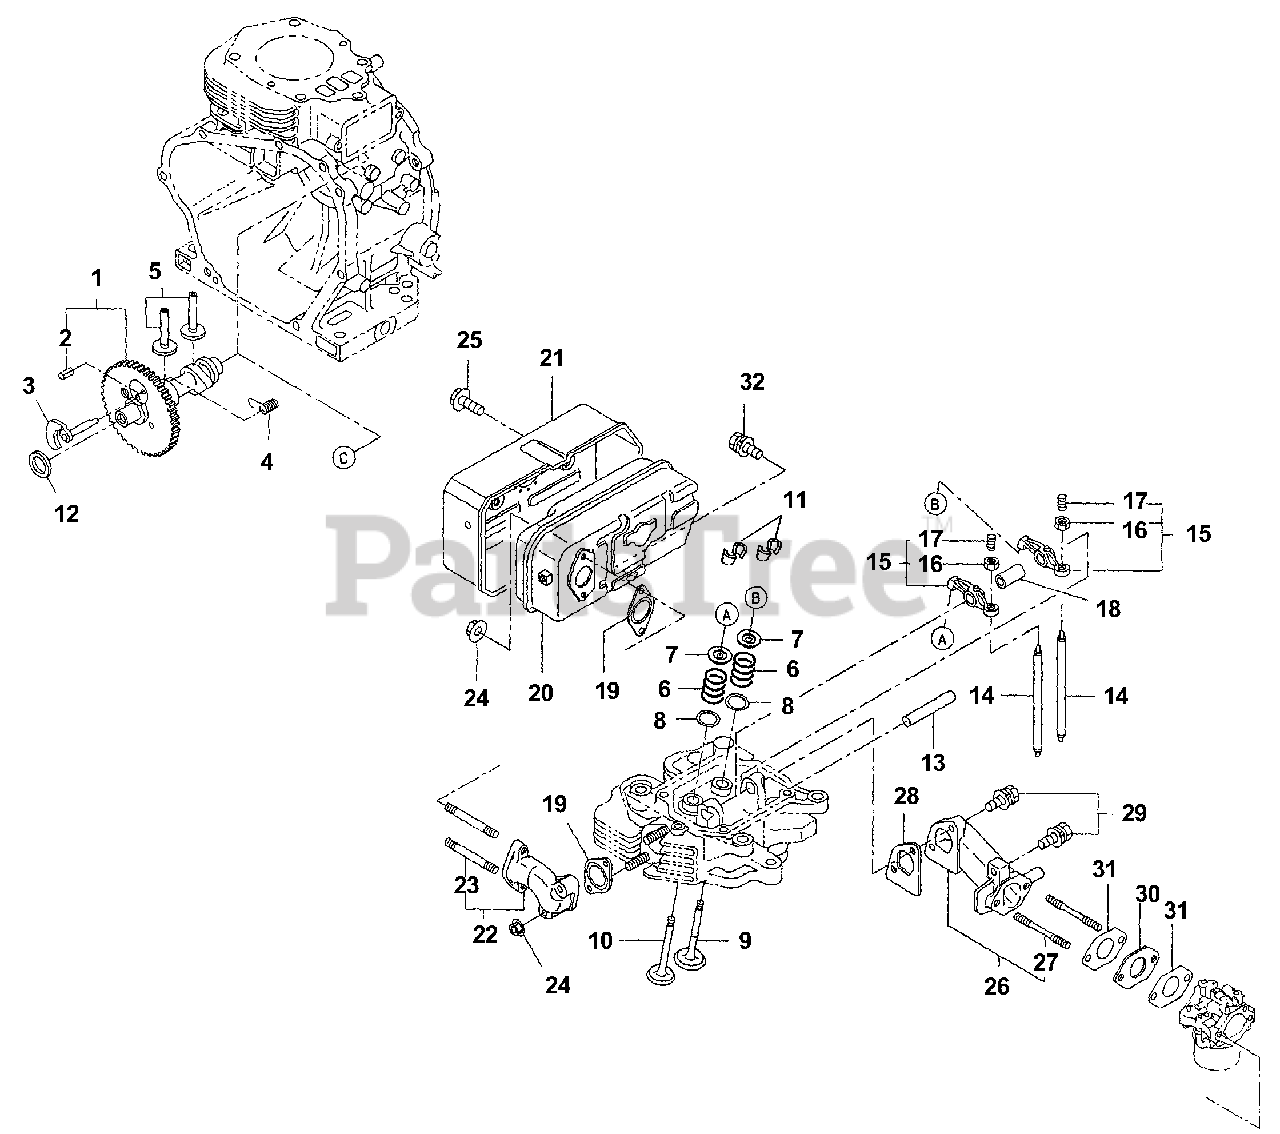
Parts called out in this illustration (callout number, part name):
1	Camshaft
2	Spring pin
3	Release lever cp
4	Return spring
5	Tappet
6	Valve spring
7	Spring retainer
8	Washer
9	Intake valve
10	Exhaust valve
11	Collet, valve
12	Spacer T=0.6
13	Rocker shaft
14	Push rod cp
15	Rocker arm Ay
16	Nut
17	Adjusting Screw
18	Spacer / Rocker Shaft
19	Gasket, exhaust
20	Muffler cp
21	Muffler Cover cp
22	Exhaust Pipe cp
23	Stud
24	Flange Nut
25	Flange Bolt
26	Intake Pipe cp
27	Stud
28	Gasket, In. Pipe
29	Bolt and Washer AY
30	Insulator
31	Gasket, insulator
32	Bolt and Washer AY
